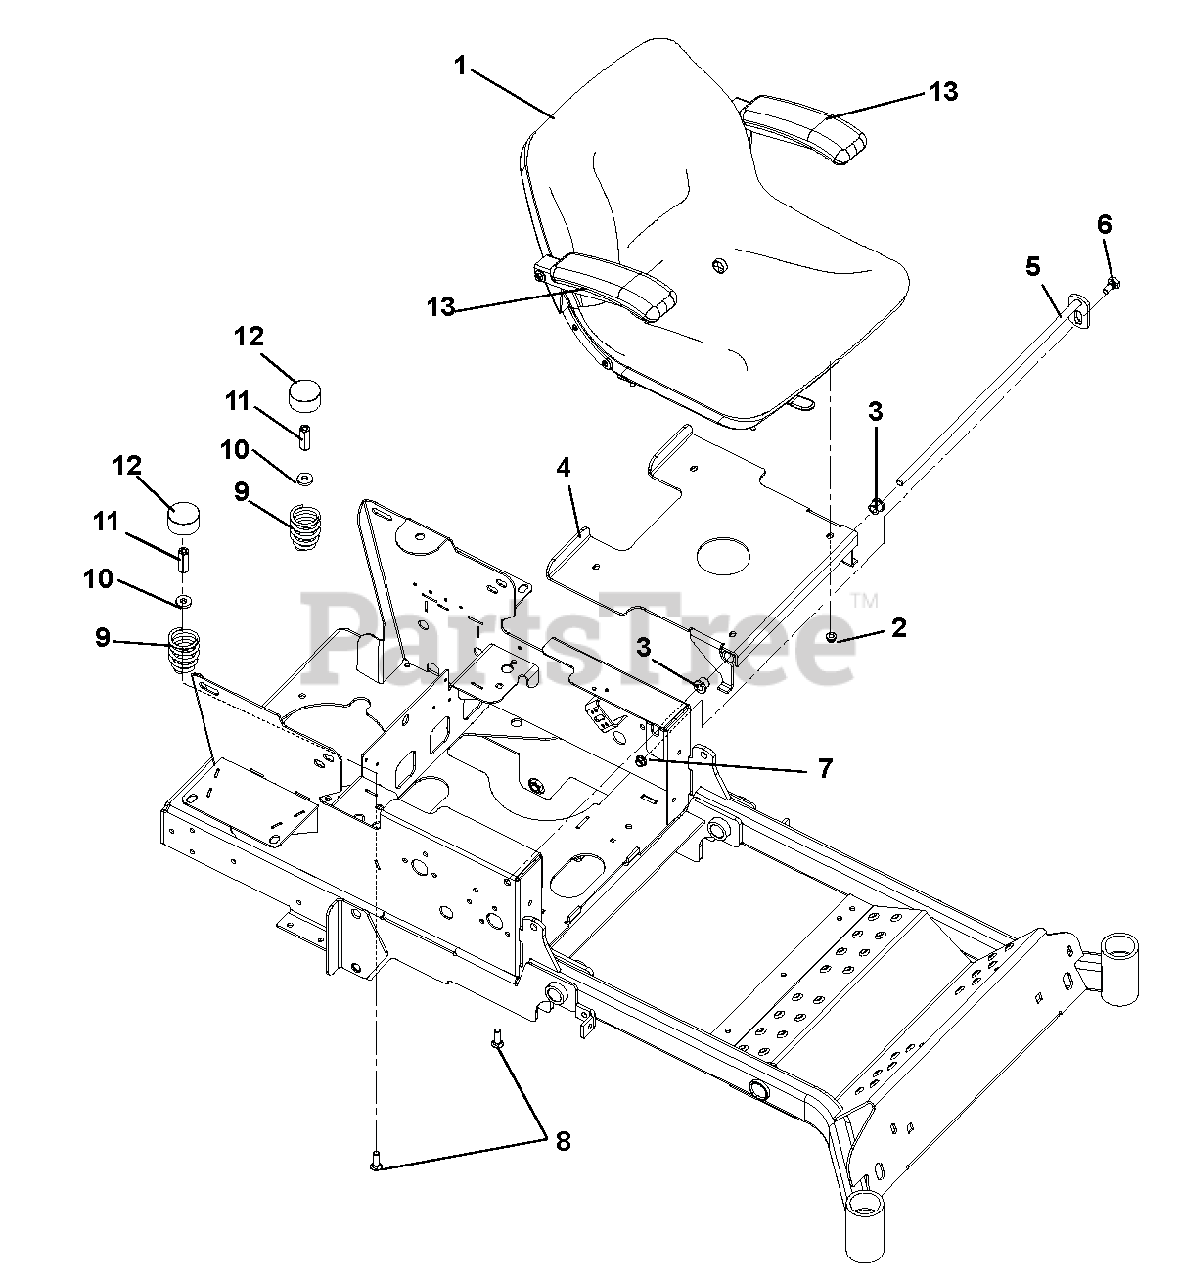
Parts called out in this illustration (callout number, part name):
1	SEAT, MILSCO XB-180
1	SWITCH- SNAP MTG N.O.
2	@NUT-LK-NYL-FLG .31-18 YWZC
3	BSHG, FLG .516X.750X.625X.937
4	WLDMT, SEAT PLATE
5	WMT, SEAT SHAFT
6	BLT,SHLDR EP .38-16X.30 HEX YZ
7	@NUT-SPNLK-FLG .375-16 YWZC
8	@BLT-RDHDSQNK .38-16X1.25 G5YZ
9	SPRING, SEAT
10	WSHR-FL-STL .406X1.00X.188 YWZ
11	NUT COUPLING .375-16X1.75
12	HUB CAP
13	KIT, SEAT ARM RESTS
